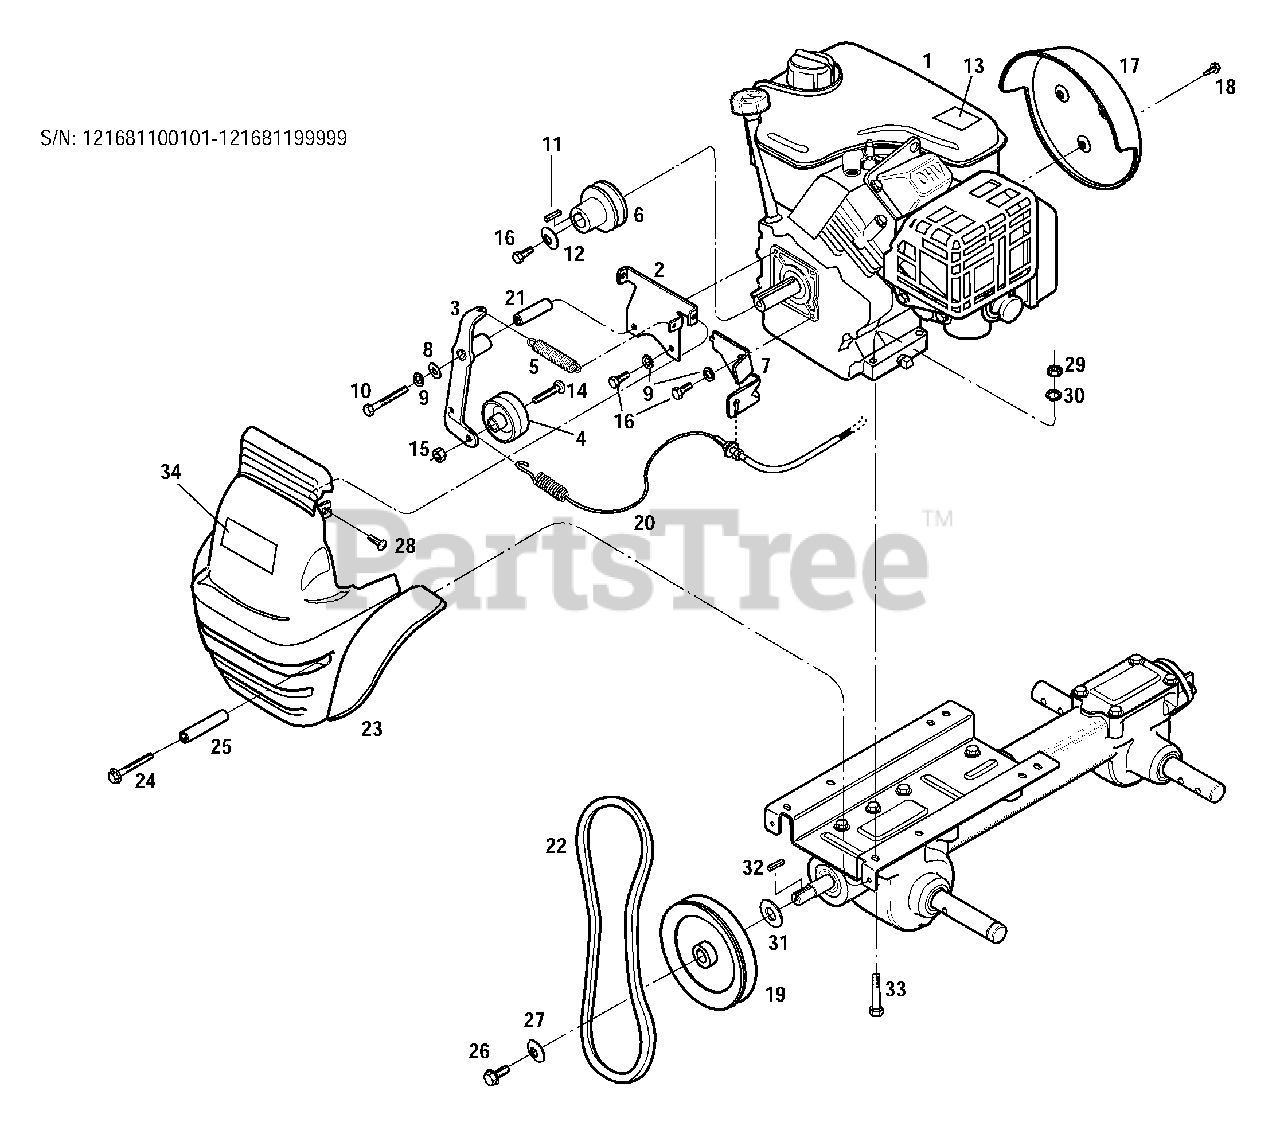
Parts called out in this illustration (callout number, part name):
1	Engine, 5HP OHV Tecumseh Enduro
2	Bracket, Belt Cover
3	Idler Arm
4	Idler Pulley
5	Spring, Return
6	Engine Pulley
7	Bracket, Cable Mount
8	Washer .75 x .32 x .09 ZP
9	Washer, Spring Lock 0.312
10	Hex Hd. Screw, 5/16-24 x 2-1/2
11	Key, 3/16 x 1 Square
12	Lock Washer, Conical
13	Decal, Stabilization
14	Button Head Screw, 3/8-16 x 1-3/4
15	Hex Lock Nut, 3/8-16
16	Screw, Hex Hd, 5/16-24 x 3/4
17	Recoil Cover
18	Screw, Hex Flange #8-18 x 3/8
19	Transmission Pulley
20	Wheel Drive Cable
21	Bushing-Idler Arm
22	V-Belt
23	Belt Cover w/Fenders
24	Screw, 1/4-20 x 5/8, Self Tapping
25	Spacer
26	Screw, Hex Hd 5/16-24 x 3/4
27	Belleville Washer
28	Screw, 1/4-20 x 1/2
29	Lock Washer, .312
30	Hex Nut, 5/16-18
31	Washer, 1.25 x .687 x .75
32	Key, 3/16 x 1 Square
33	Screw, Hex Hd, 5/16-18
34	Decal, Logo
